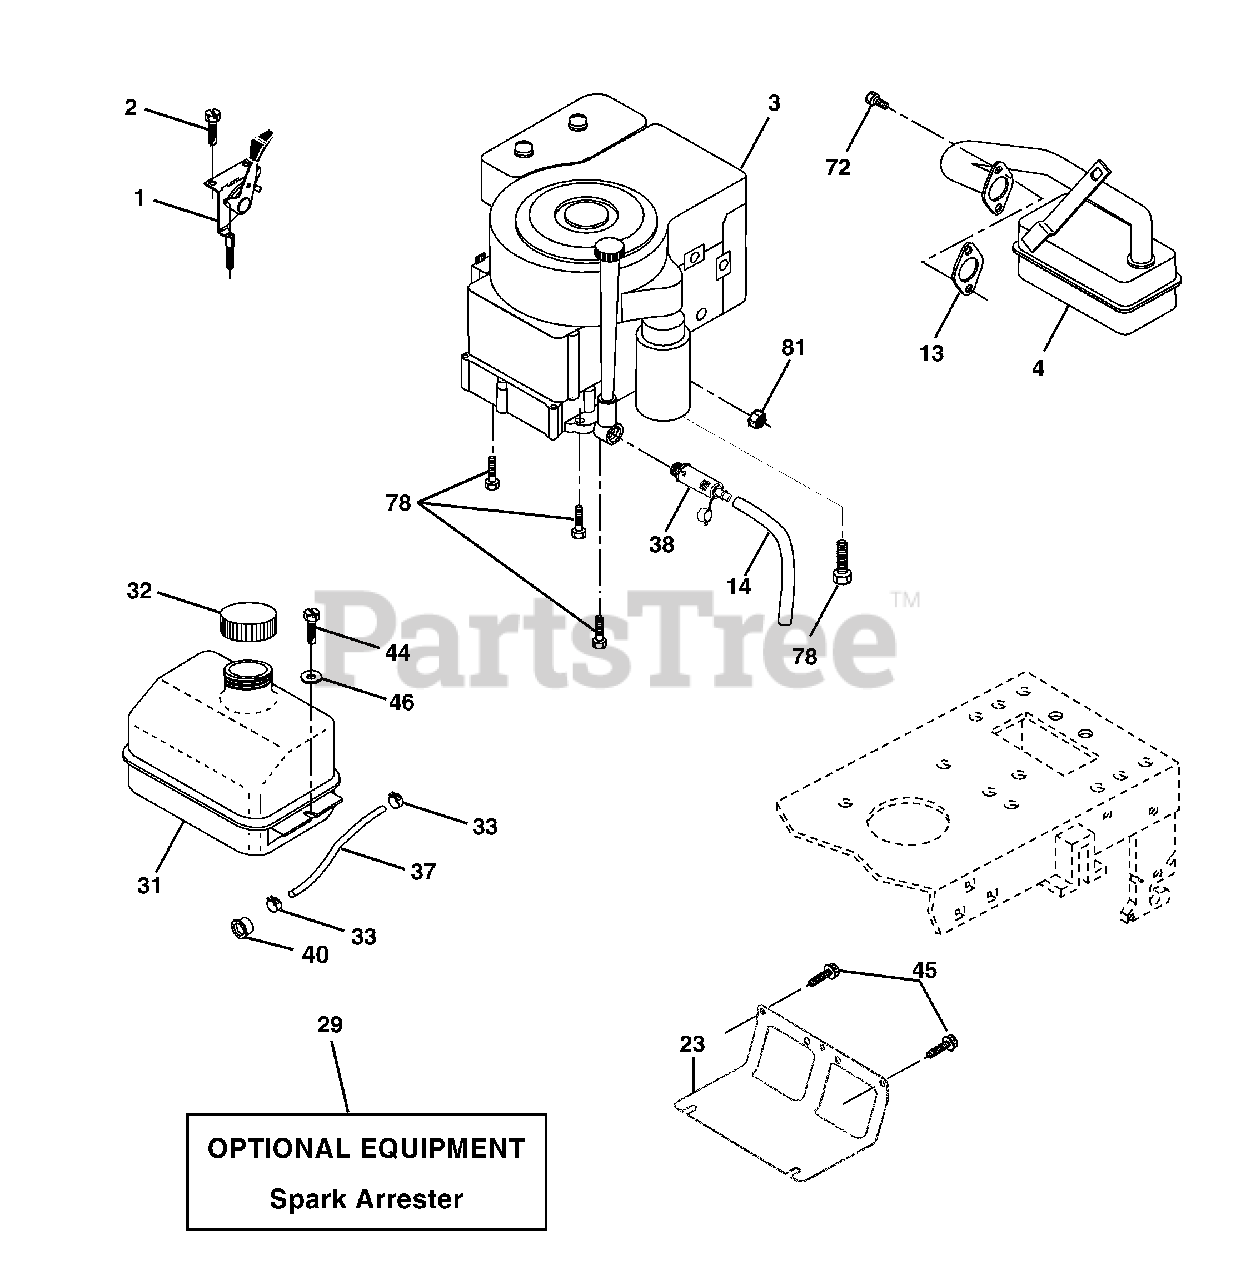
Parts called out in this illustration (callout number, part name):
1	Control Throttle /Choke Flag
2	Screw Hex Thd Cut 1/4-20 x 1/2
4	Muffler Exhaust B&S Lt
13	Gasket 1 313 Id Tin Plated
14	Tube Drain Oil Easy
23	Shield Browning/Debris Guard
29	Arrestor Spark
31	Tank Fuel 1 25 Fr
32	Cap Asm Fuel W/sym Vented
33	Clamp Hose Blk
37	Line Fuel 20"
38	Plug Drain Oil Easy
40	Bushing Snap Nyl Blk Fuel Line
44	Screw Hexwsh Thdrol 1/4-20 x 3/4
45	Screw Hex Wsh Thdrol 3/8-16
46	Washer 9/32 x 7/8 x 16 Ga.
72	Screw Socket Head 5/16-18 x 1
78	Screw Thdrol 3/8-16 x 1-1/4
81	Nut Keps Hex 1/4-20 unc
